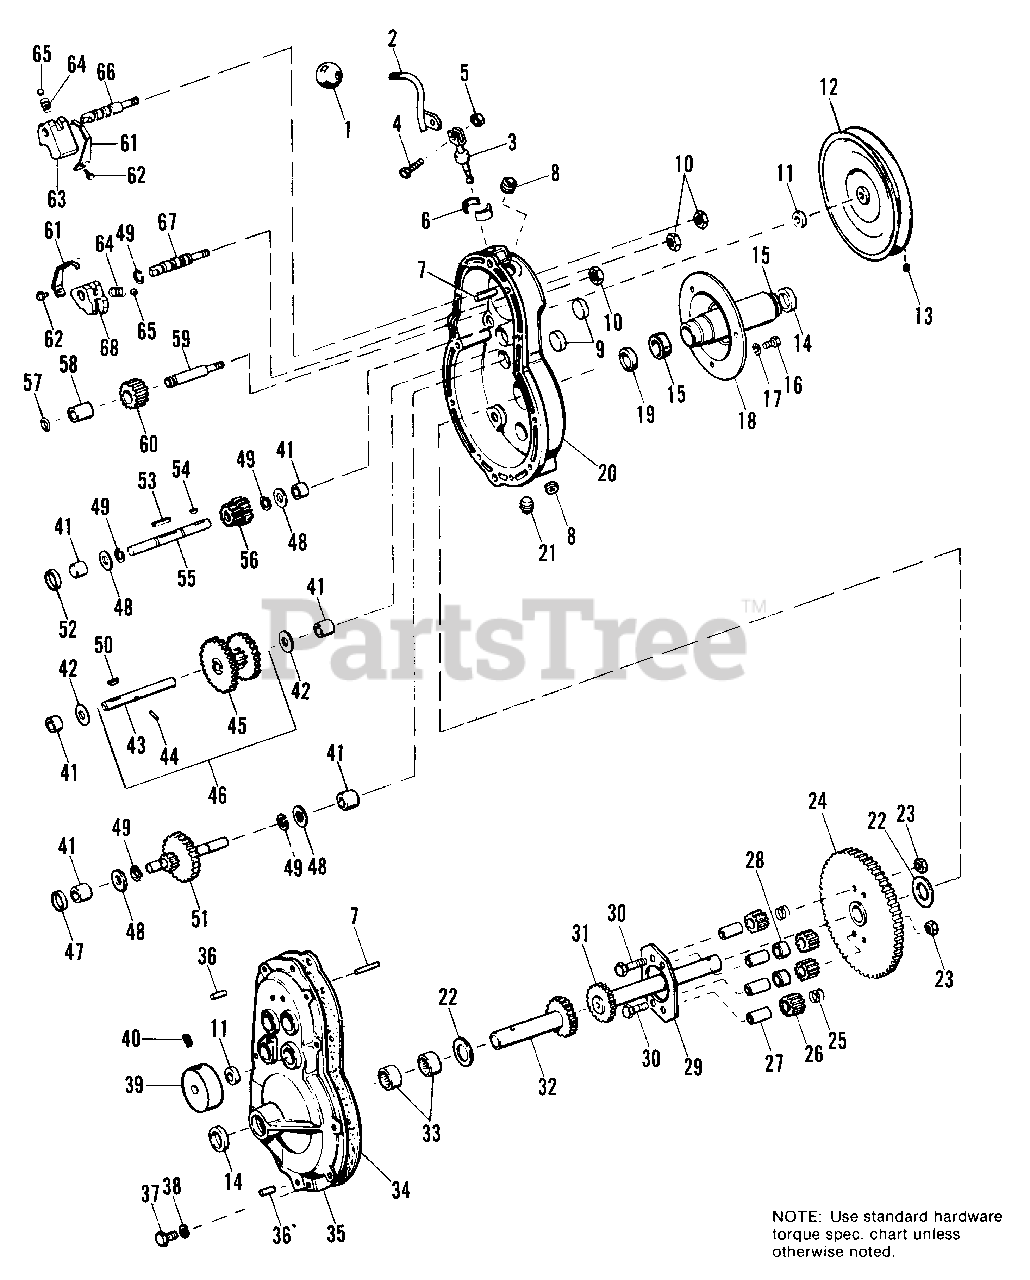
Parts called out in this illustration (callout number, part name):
2	LEVER ASSY., Shift
3	ROD ASSY., Shift
4	CAPSCREW, Hex Hd., 1/4-20 x 3/4
5	LOCKNUT, Hex, 1/4-20
6	BUSHING, Half
7	PIN ASSY., Roll
9	PLUG, Expansion
10	NUT, Hex, Full, 7/16-14
12	PULLEY, Drive
13	SETSCREW, 3/8-16 x 3/8
16	CAPSCREW, Hex Hd., 3/8-16 x 7/8
17	LOCKWASHER, 3/8
18	HOUSING ASSY., Axle
20	CASE ASSY., Gear
21	PLUG, Pipe
23	LOCKNUT, Hex, 3/8-16
24	GEAR ASSY., Drive
26	PINION, Diff.
27	SPINDLE, Diff.
28	SPACER, Diff.
29	PLATE, Diff.
30	CAPSCREW, Hex Hd., 3/8-16 x 2-1/2
31	SHAFT ASSY., Axle, R.H.
32	SHAFT ASSY., Axle, L.H.
33	BEARING, Roller;
35	COVER ASSY., Gear Case
36	PIN, Roll, 3/8 x 1
37	CAPSCREW, Hex Hd., 5/16-18 x 1-1/4
38	LOCKWASHER, 5/16
39	DRUM, Brake
40	SETSCREW, 5/16-18 x 5/16
43	SHAFT, Brake
44	PIN, Dowel
45	CLUSTER ASSY., Gear
46	SHAFT & GEAR ASSY.
47	PLUG, Expansion
49	RING, Retaining
50	KEY, 5/32 x 5/8 Dia.
51	GEAR & SHAFT ASSY.
52	PLUG, Expansion
54	KEY, 3/16 x 3/4
55	SHAFT, Pulley
56	PINION ASSY., Hi-Lo
58	BEARING, Roller
59	SHAFT, Reverse, Pinion
60	PINION, Reverse
62	SCREW, Hex, Washer Hd., 5/16-18 x 5/16
63	FORK, Shift, I & II
66	SHAFT, Shift, Hi-Lo
67	SHAFT, Shift, Reverse-Lo
68	FORK, Shift, Reverse
